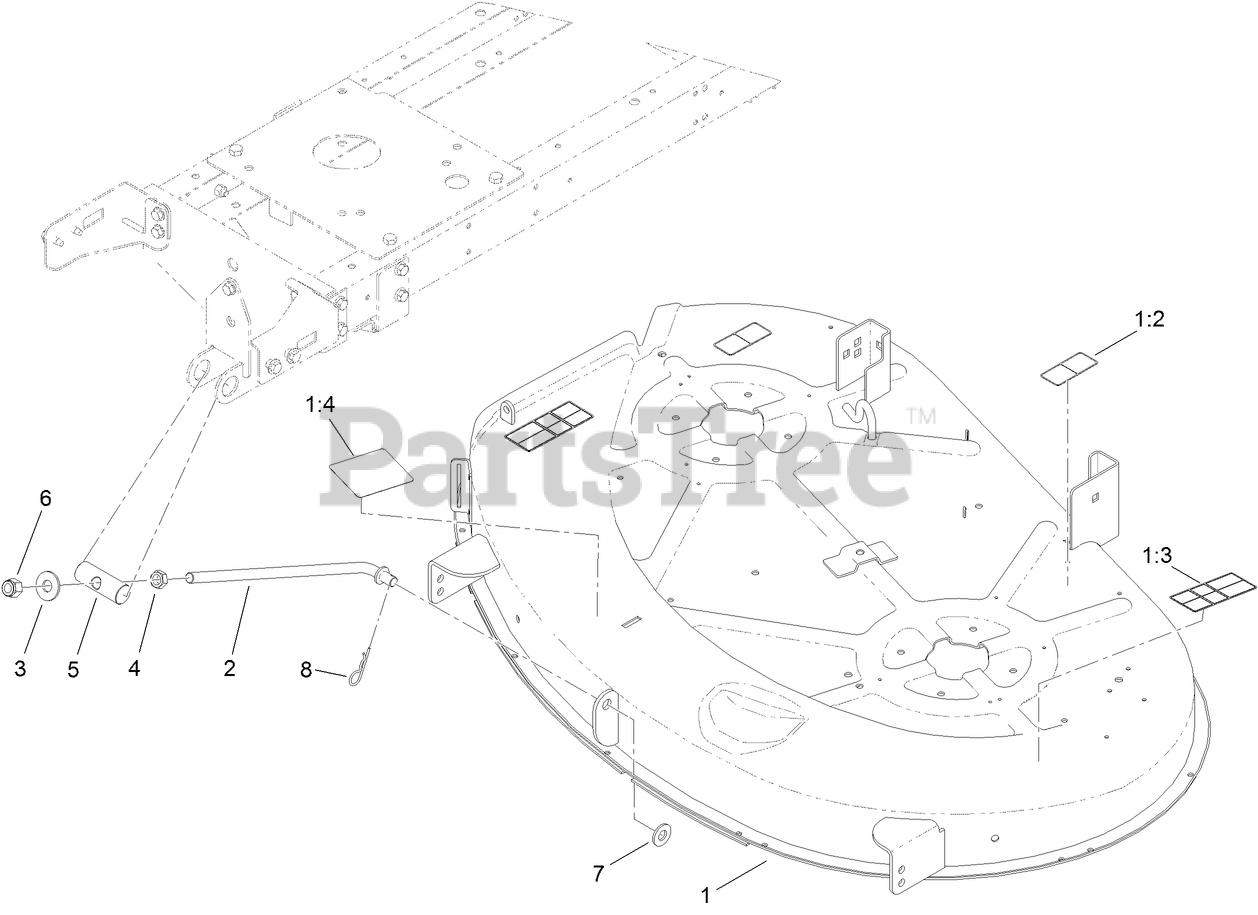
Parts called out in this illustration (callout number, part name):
1	42 INCH DECK ASM
1:2	DECAL-WARNING
1:3	DECAL-WARNING
1:4	DECAL-GUIDE, BELT
2	ROD-PIVOT
3	WASHER-FLAT
4	NUT-JAM
5	PIN-PIVOT
6	NUT-HEX
7	WASHER-THRUST
8	PIN-HAIR
